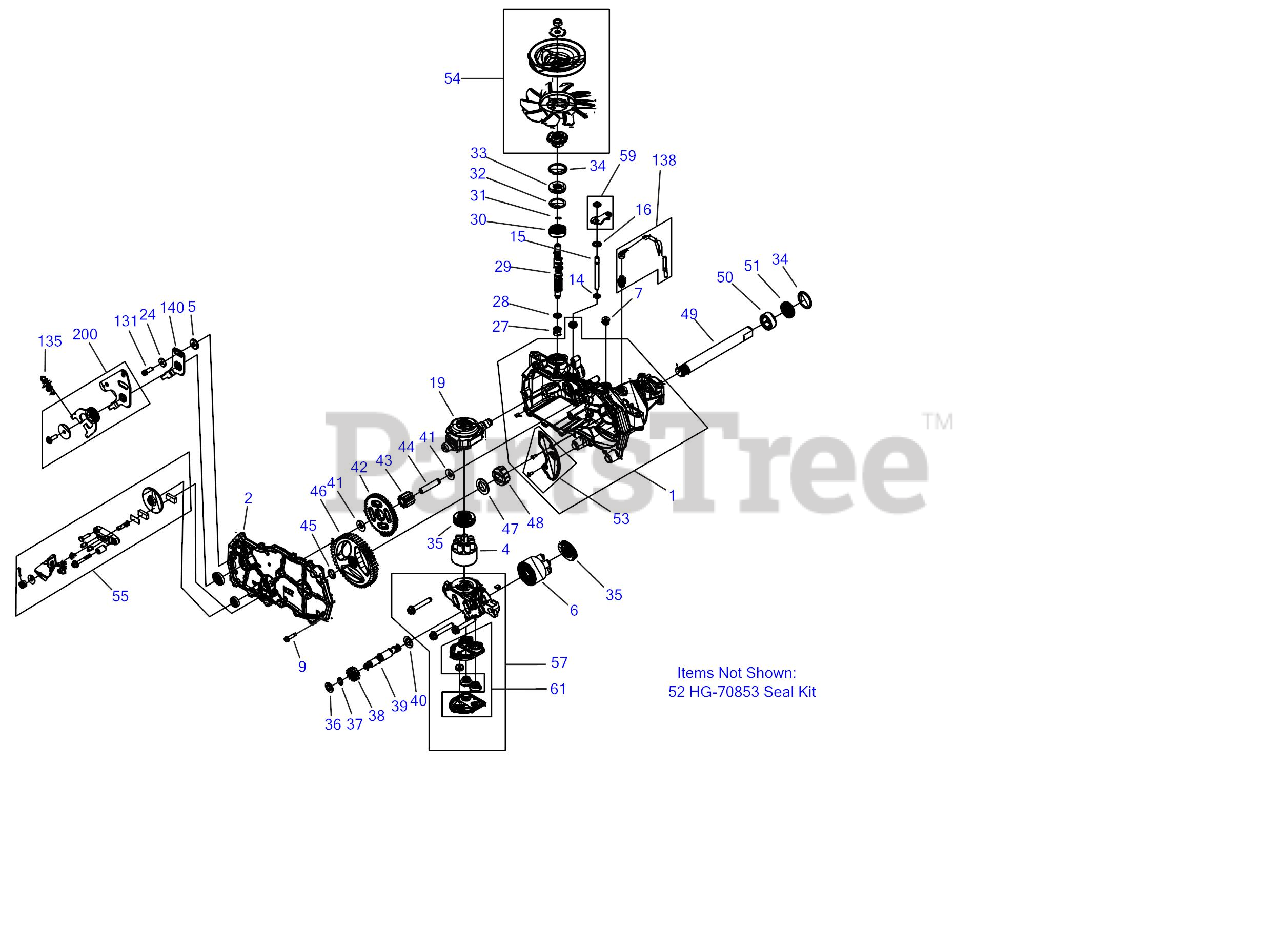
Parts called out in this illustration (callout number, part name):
1	Kit, Housing, Main, RH
2	Kit, Housing, Side, RH
4	Kit, Block, 7 Piston
5	Spacer, .320 x 1.005 x .150
6	Kit, Block, 10cc Cylinder
9	Screw, Hex Washer
14	Ring, Retaining .375 External
15	Rod, Bypass
16	Ring, Ret .375 External
19	Trunnion, Swashplate
24	Washer, .34 x .88 x .06
27	Spring, Block
28	Washer, .59 x .79 x .04
29	Shaft, Input
30	Ball Bearing 17 x 40 x 12
31	Ring, Reatining
32	Washer, 1.23 x 1.57 x .04
33	Seal, Lip 17 x 40 x 7
34	Ring Retaining Internal
35	Thrust Bearing, 30 x 52 x 13
36	Washer, .63 x 1.00 x .05
37	Ring, Reatining, Motor Shaft
38	Gear, 13T Pinion
39	Shaft, Motor
40	Washer, .71 x 1.16 x .04
42	Gear, 10T/48T
43	Gear, 10T Jackshaft
44	Pin, Jackshaft
45	Ring, Spiral Retaining-87
46	Gear, Bull 52T
47	Washer, 1.018 x 1.571 x .105
48	Buahing, Sleeve (Inboard)
49	Shaft, Axle, 1.00 x 11.70 DD
50	Bushing, 1.003 x 1.571 x .625
51	Seal, Lip, TC4, 1.00 x 1.577 x .27
52	Kit, Seals & Rings
53	Kit, Expansion Plate RH
54	Kit, Fan & Pulley
55	Kit, Brake Arm
57	Kit, Center Section RH
59	Kit, Bypass Arm
61	Kit, Filter
131	Socket Cap Screw, 5/16-24 x 7/8
135	Spring, Extension
138	Kit, Breather
140	Arm, Neutral Right
200	Kit, RTN Bidirectional
